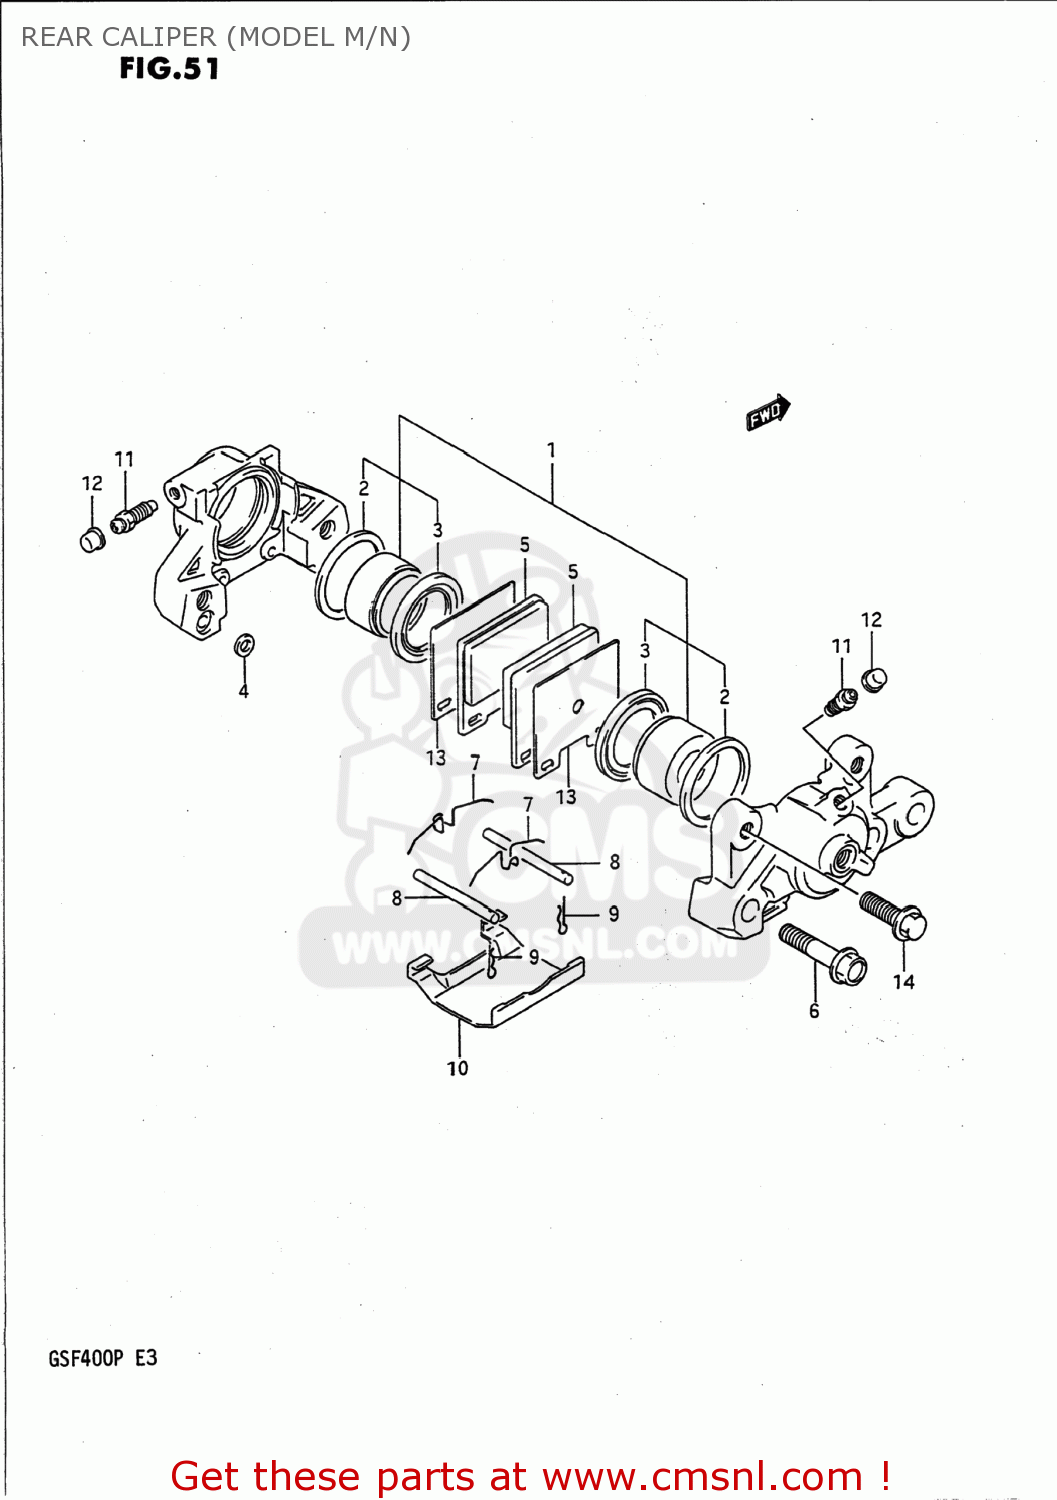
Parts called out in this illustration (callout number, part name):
1	PISTON SET
2	SEAL,PISTON
3	BOOT
4	SEAL,JOINT
5	PAD,BRAKE
6	BOLT,HOUSING
7	SPRING
8	PIN,PAD
9	CLIP,PAD PIN
10	COVER
11	BLEEDER
12	CAP,BREATHER
13	SHIM,PAD
14	BOLT
